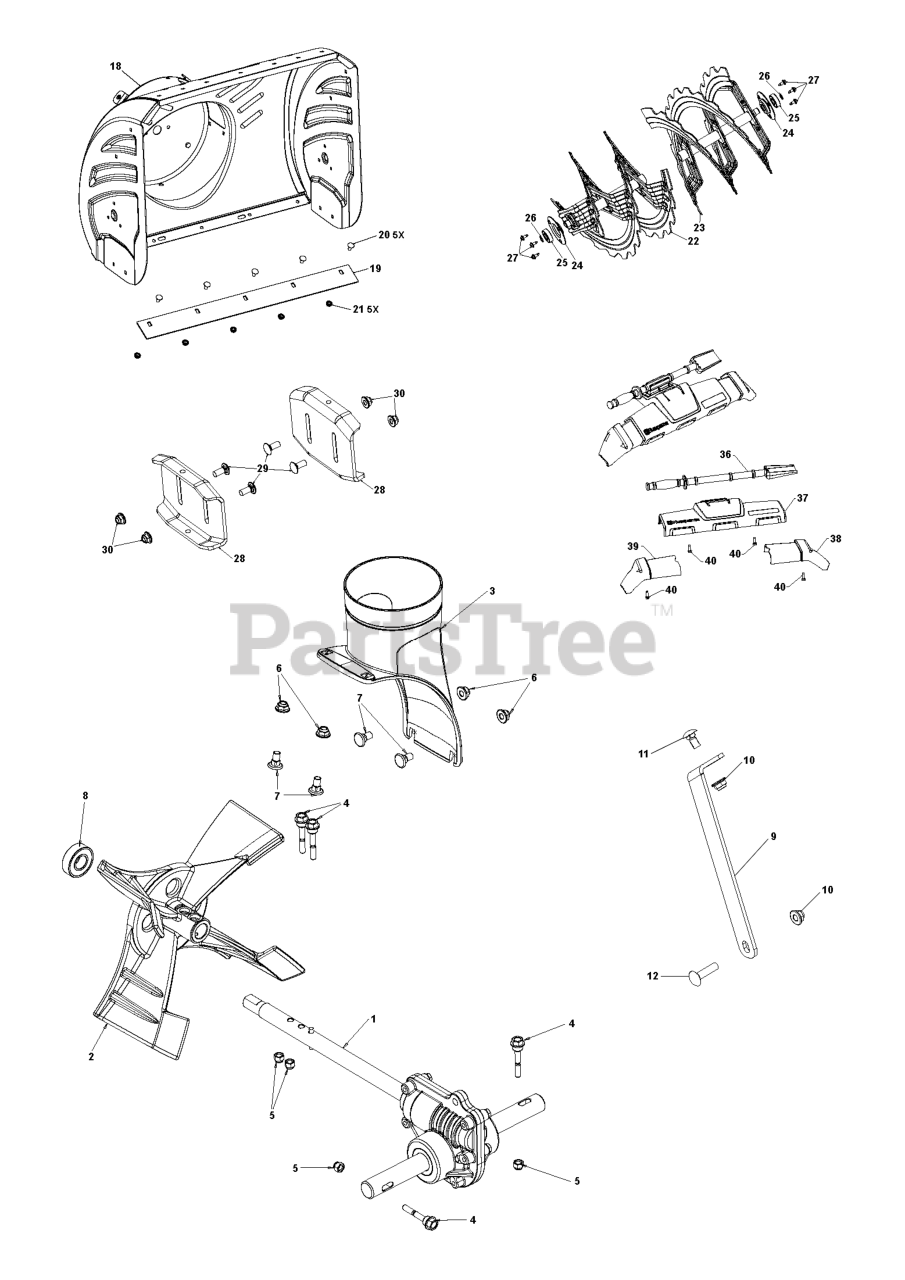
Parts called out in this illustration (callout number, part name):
1	GEARBOX CAST DD SHAFT
3	CHUTE BASE CAST ALUM HUSQ SIL
4	BOLT SHEAR HX HD 1/4-20 CLEAR
5	NUT HEXAGON 1/4-20 ST ZPB
6	NUT HEX FLG NYLOCK BLK 5_16-1
7	BOLT CARR WAFER BLK 5_16-18 X
9	SUPPORT.GEARBOX.LS.498
10	NUT HEX FLG NYLOCK BLK 5_16-1
11	BOLT CAR BLK 5/16-18 X 5/8
12	BOLT.CARRIAGE.5/16-18
18	HOUSING ASSY KIT AUG.HSG.58618
19	PLATE.SHAVE.27.LS.SNOW.BLACK
20	BOLT ROUND HEAD SQUARE NECK BO
21	NUT.FLANGE.5/16
22	AUGER.RIB.27.RH.LS.GREY
23	AUGER.RIB.27.LH.LS.GREY
24	SUPPORT.BEARING.SINGLE.STAGE.B
25	BEARING.BALL.MANDREL
26	RETAINING RING LT
27	SCREW HEXWSHR 1/4-20X3/4
28	SKID PLATE
29	BOLT CARR BLK 5_16-18 X .750
30	NUT HEX FLG NYLOCK BLK 5_16-1
36	CLEAN OUT TOOL
37	TRIM AUGER FRONT TRIM ASSEMBLY
38	TRIM AUGER.HOUSING.WING.RH MS
39	TRIM AUGER.HOUSING.WING.LH MS
40	SCREW 14-20 X 5/8
